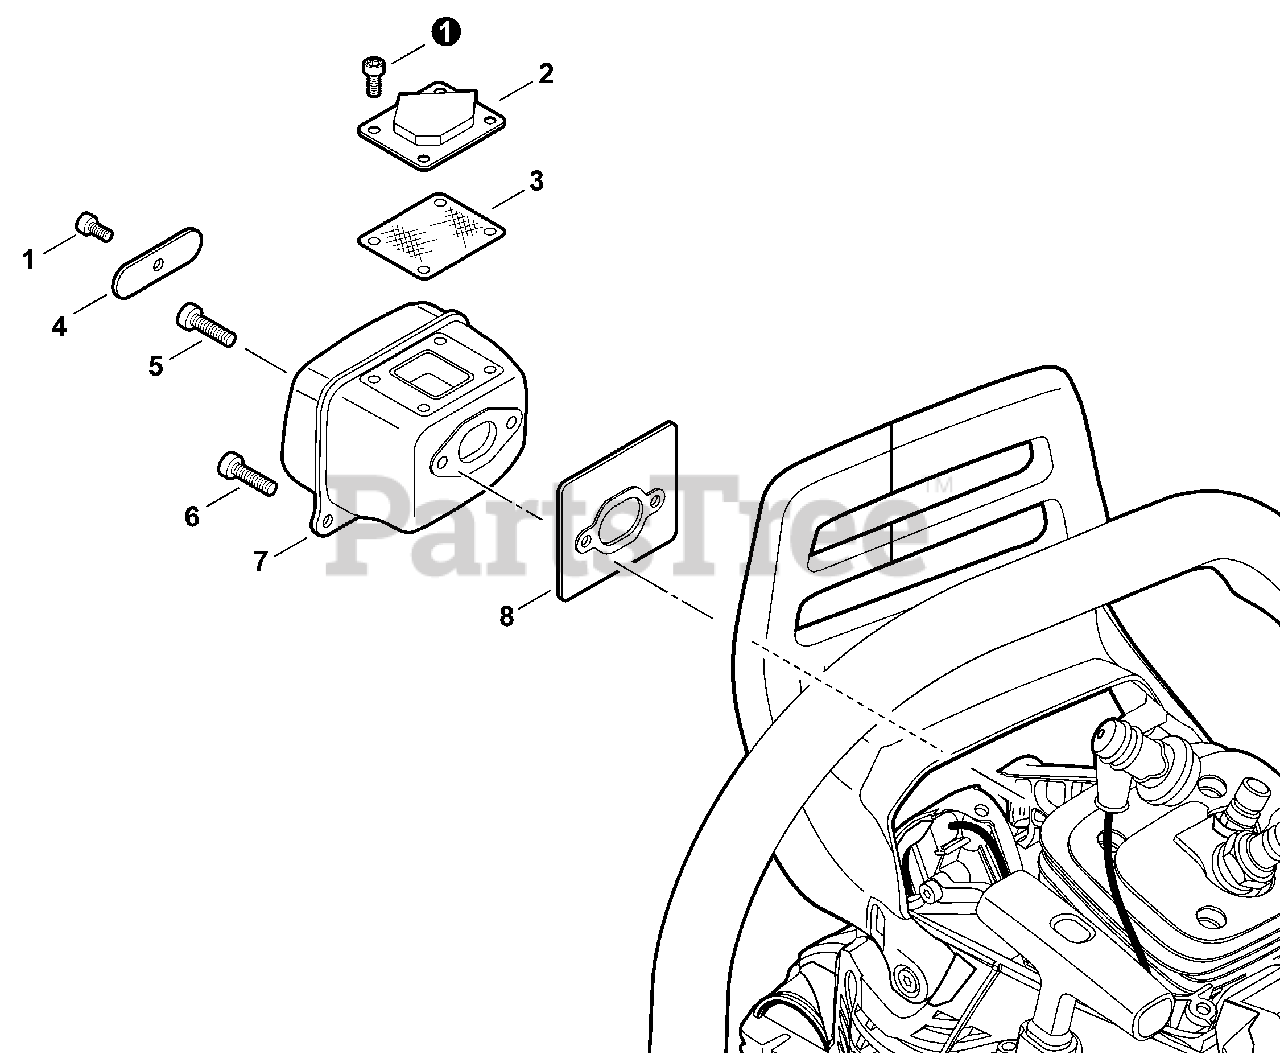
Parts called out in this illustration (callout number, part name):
1	BOLT, TORX 4×8
2	GUIDE, EXHAUST
3	SCREEN, SPARK ARRESTER
4	PLATE, MUFFLER
5	BOLT, TORX 5×20
6	BOLT, TORX 5×25
7	MUFFLER
8	GASKET, EXHAUST
